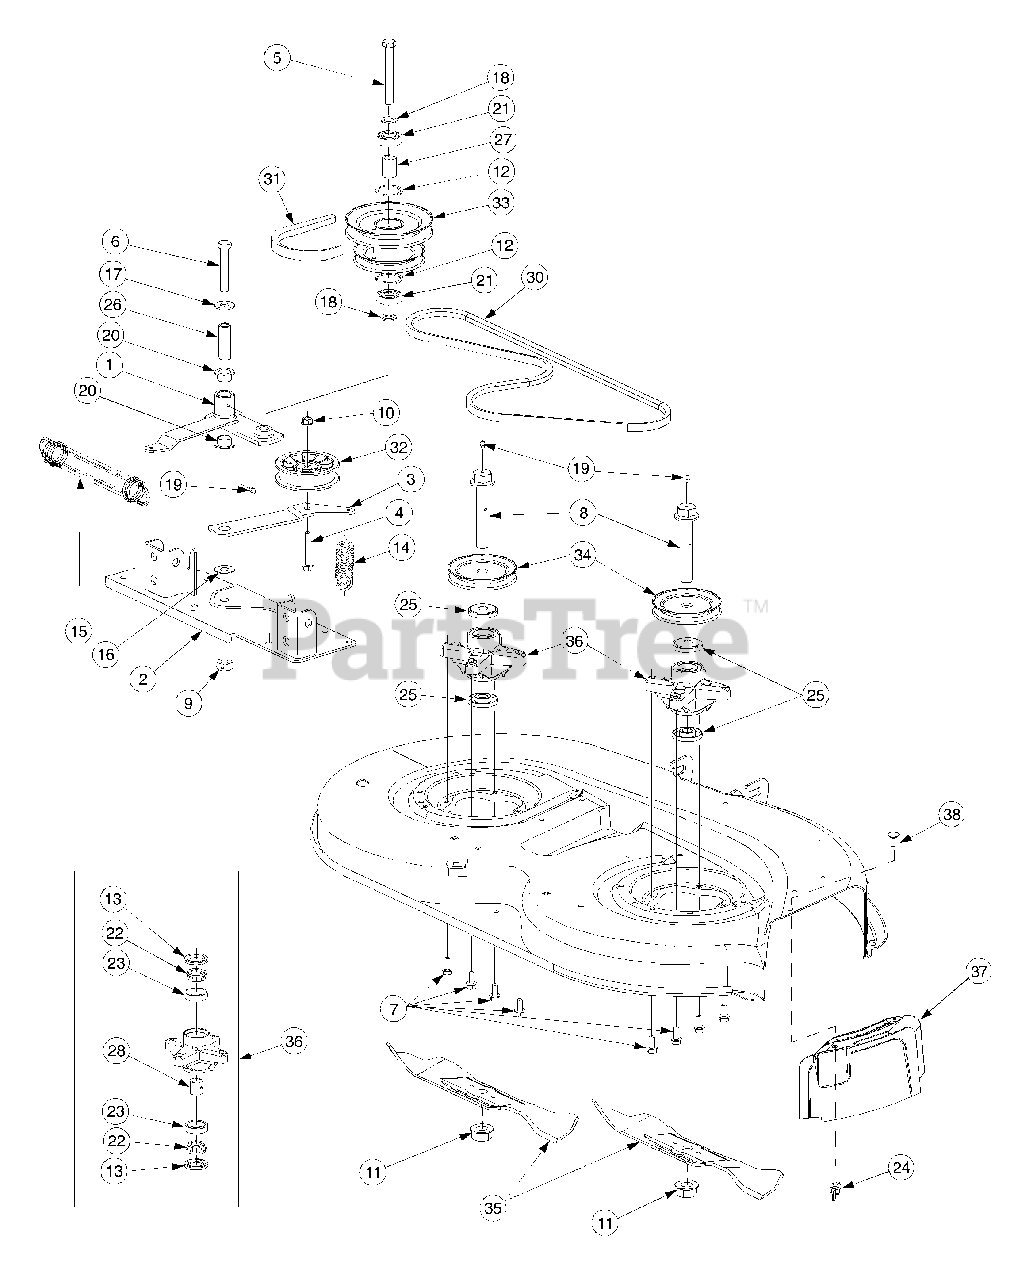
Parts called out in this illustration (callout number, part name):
1	Pivot Arm, Double Pulley
4	Screw, Hex Cap, 3/8-16 x 1.5 GR5
5	Screw, Hex Cap, 5/8-18 x 3.0 GR5
6	Screw, Hex Cap, 1/2-20 x 3.0 GR8
7	Screw, Hex Wsh Hd Tap, 5/16-18 x .75
8	Bolt, Spindle, 3/4-16 x 4.25
9	Nut, Hex Center Lock, 1/2-20
10	Nut, Hex Flange Lock, 3/8-16
11	Nut, Hex Flange, 3/4-16
12	Snap Ring, Internal
13	Seal, Oil, 1.25 x 1.874 x .25
14	Spring, Extension, .88 x 6.12
15	Spring, Extension, 1.25 x 8.15
16	Washer, Flat, .531 x 1.25 x .036
17	Washer, Flat, .531 x 1.25 x .100
18	Washer, Flat, .65 x 1.25 x .075 Hdn.
19	Fitting, 3/16 Drive Lube
20	Bearing, Flange, 3/4 ID x .53 Lg
21	Bearing, .625 ID x 1.574 OD x 470
22	Cone, Bearing
23	Cup, Bearing
24	Nut, Wing, 1/4-20
25	Spacer, Deck Spindle
26	Spacer, Idlr Brkt .50 ID x .75 OD x 2.25
27	Spacer, Pulley .635 ID x .88 OD x 1.25
28	Spacer, Bearing
30	Belt, Spindle, A-Section x 61 Lg
31	Belt, PTO, B-Section x 111.2 Lg
32	Pulley, Flat Idler, 3.5 OD
33	Pulley, Double
34	V-Pulley, 4.0 Dia
35	Blade, 3 In One, 21.20 Lg
36	Spindle, Blade
37	Plug, Mulch
38	Screw, Carriage, 1/4-20 x .62
